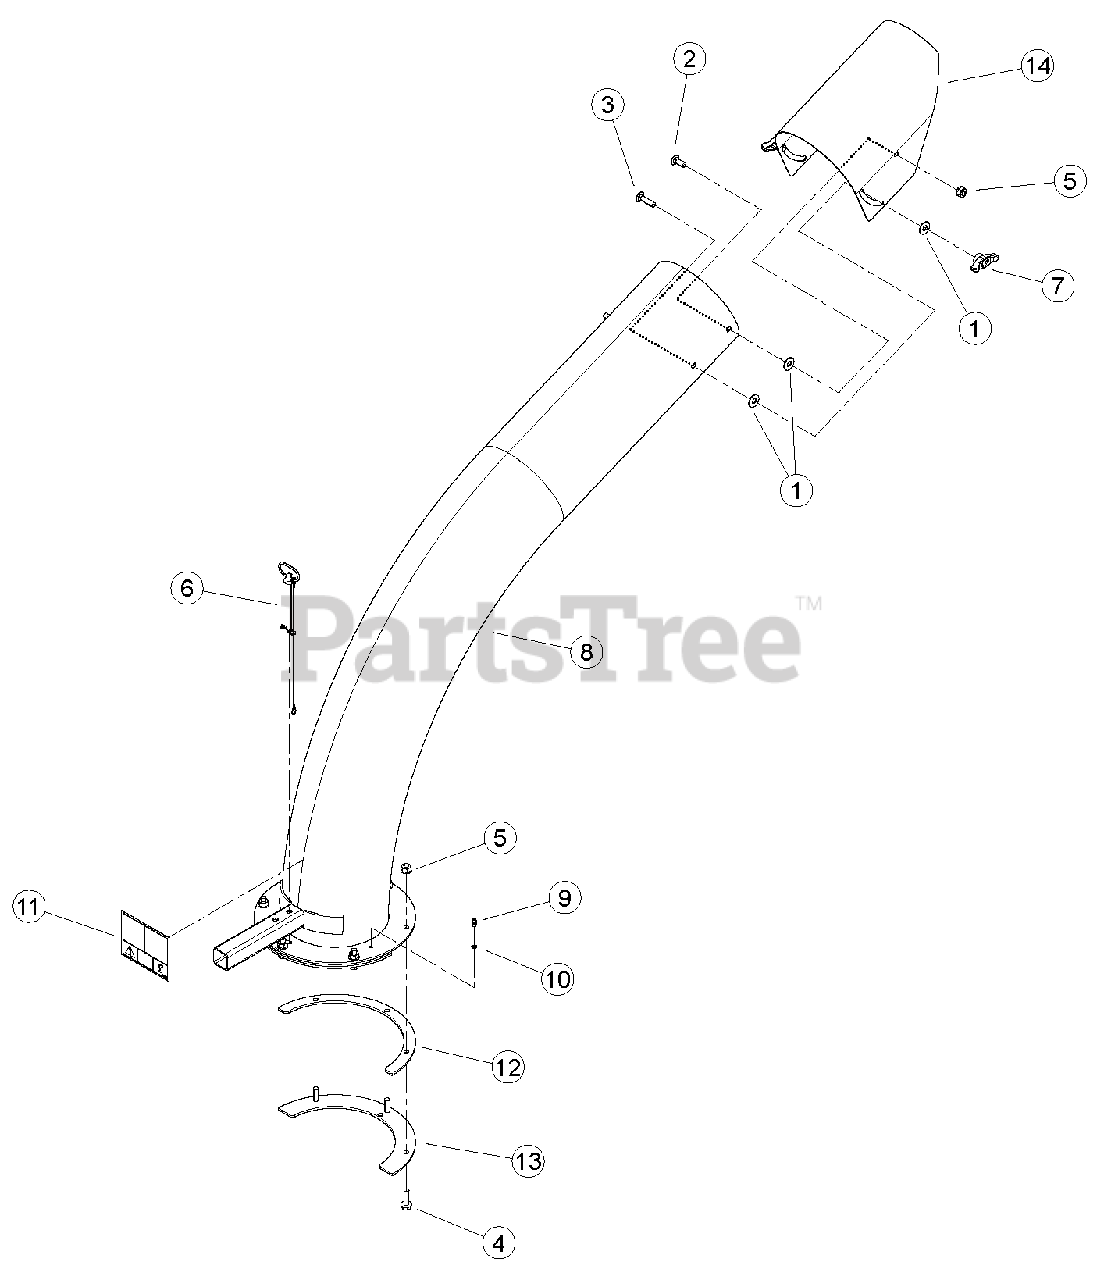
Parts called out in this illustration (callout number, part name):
1	WASHER, 3/8" FLAT ZP
2	BOLT, 3/8 X 1" GR5 CRG NC ZP
3	BOLT, 3/8 X 1-1/2" GR5 CRG NC ZP
4	BOLT, 3/8 X 1-1/4 FLANGE NC
5	NUT, 3/8-16 NYLOCK FLANGE
6	PIN, 3/8 X 4.25" DISCHARGE
7	KNOB, 3/8-16 UNC FEMALE TEE
8	ASSEMBLY, 8 INCH DISCHARGE CHUTE
9	FITTING, 1/4 SELF-TAP GREASE
10	WASHER, FLAT .254 X .400 X .048
11	DECAL, DISCHARGE DEBRIS & LOCK
12	RING, DISCHARGE SPACER
13	RING, DISCHARGE CLAMP
14	CAP, 8 INCH DISCHARGE CHUTE
